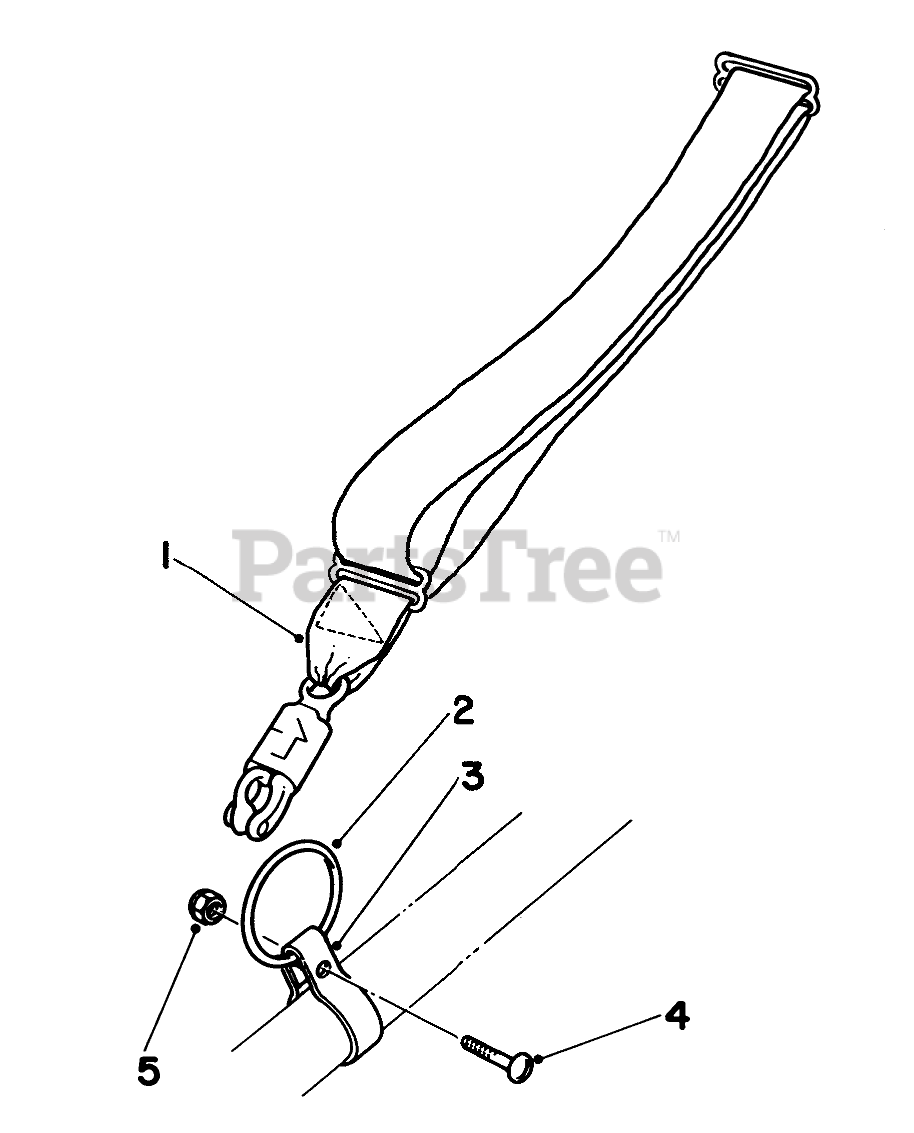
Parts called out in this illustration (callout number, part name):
1	Shoulder Strap
2	Ring
3	Clamp
4	10-24 X 5/8 PAN HD MS
5	NUT-LOCK, NI
